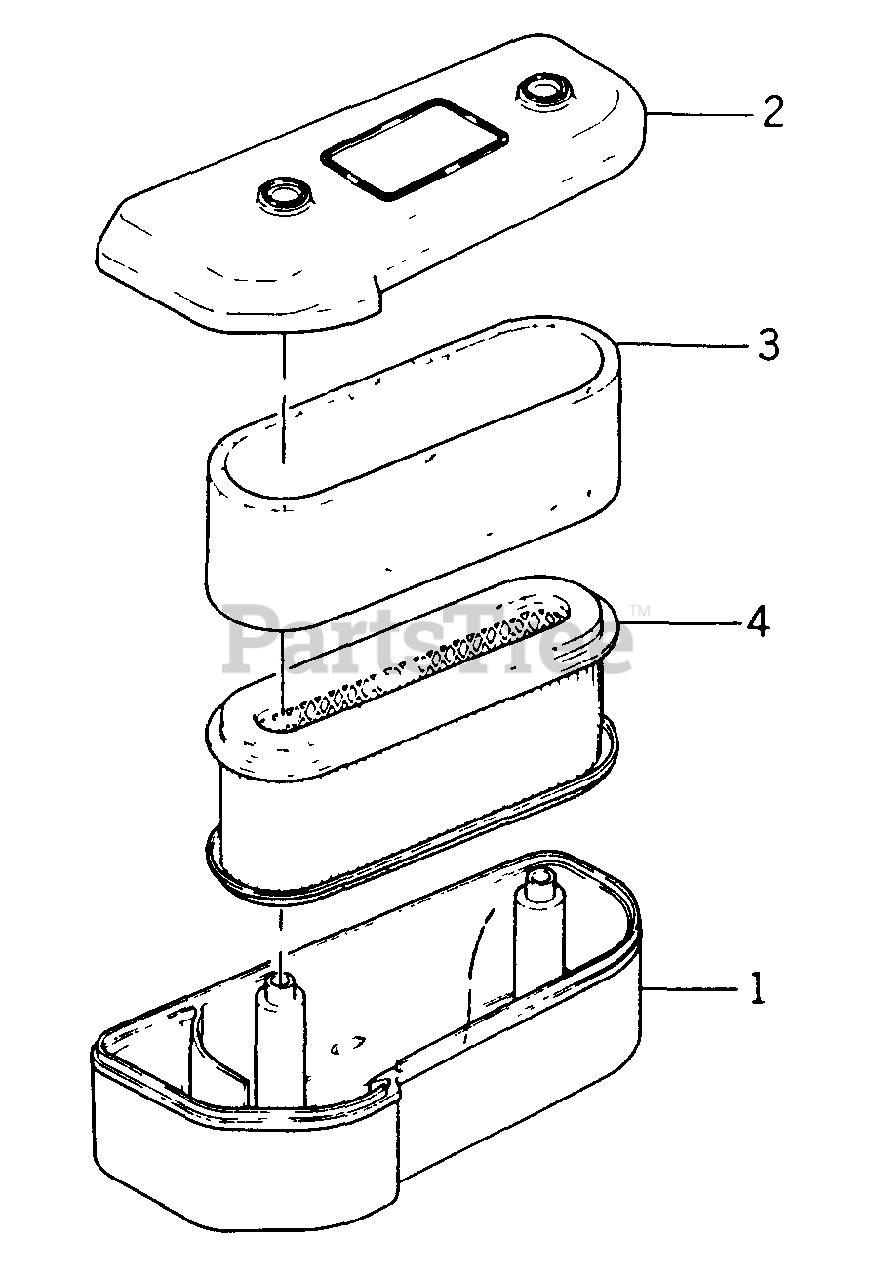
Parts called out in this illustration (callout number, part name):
1	CASE, air filter
2	CAP, air filter
3	ELEMENT, air filter
4	ELEMENT, air filter
